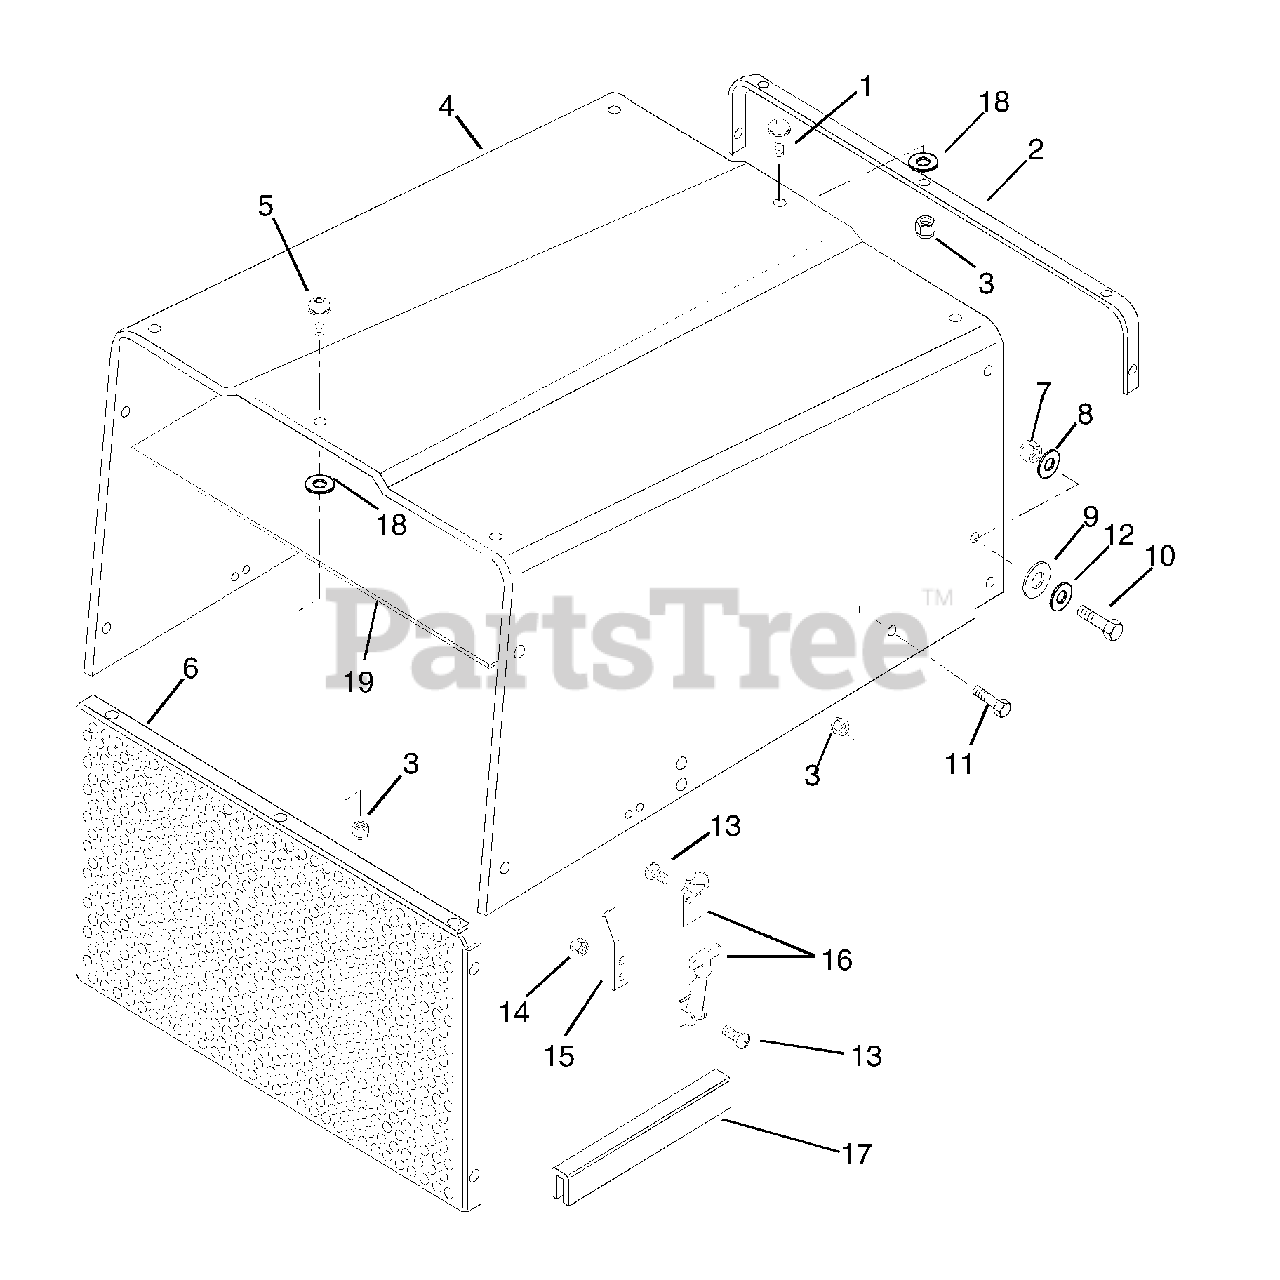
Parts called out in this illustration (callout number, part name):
1	Screw-Machine .25-20 X .75
2	Brace, Hood
3	Nut-Locking-Center .25-20
4	Hood, Engine
5	Screw-Machine .25-20 X .50
6	Panel, Hood
7	Nut-Locking-Center .38-16
8	Washer-Flat-Steel .406 x .812 x .065
9	Washer-Flat-Nylon .375 X .75 X .060
10	Bolt-Hex .38-16 x 1.00 Grade 5
11	Bolt-Hex .25-20 x .75 Grade 5
12	Washer-Flat Steel .380 x 1.50 x .125
13	Screw-Machine 10-24 x .50
14	Nut-Locking w/Insert 10-24
15	Plate, Guide
16	Latch
17	Strip, Cowl
18	Washer-Flat-Steel .265 x .50 x .087
19	Sound Pad
